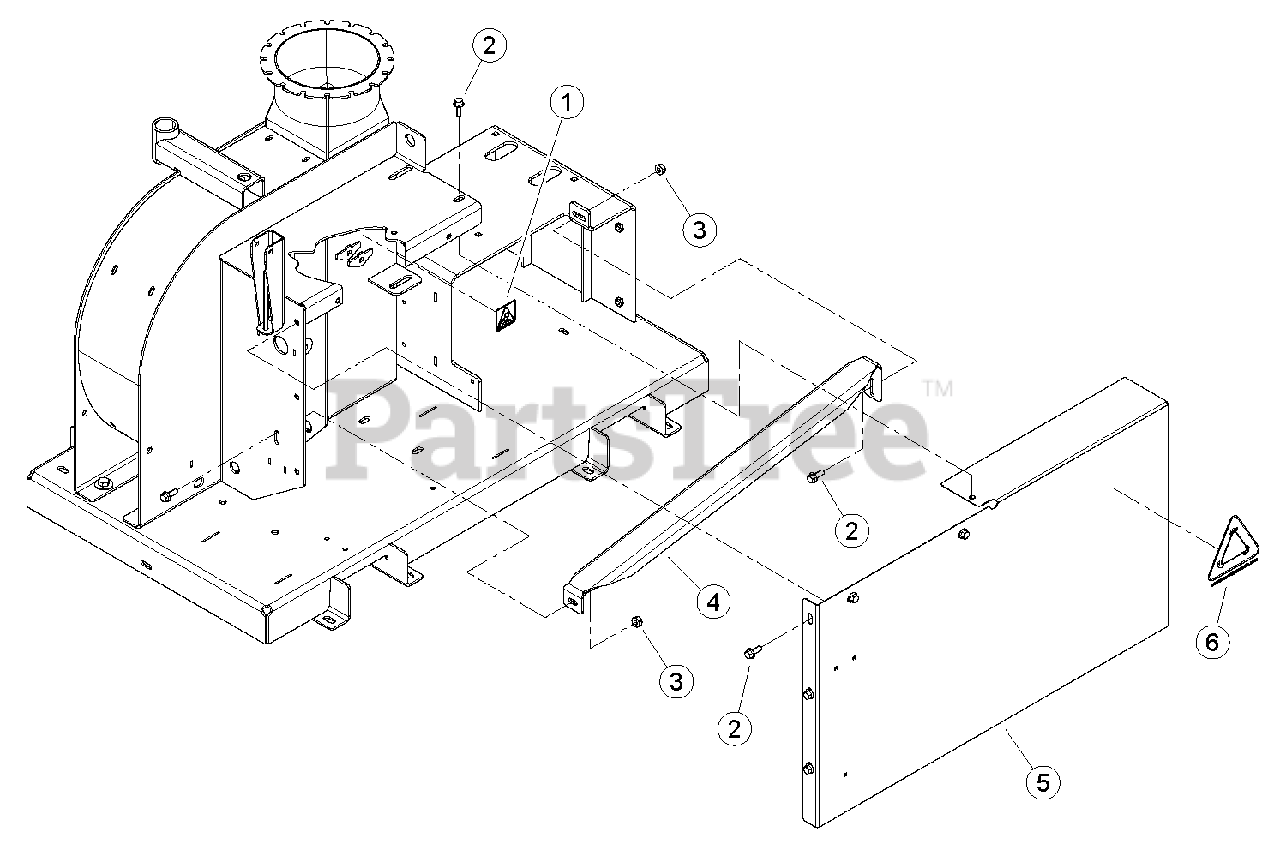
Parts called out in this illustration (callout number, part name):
1	DECAL, SHIELD DANGER ISO
2	BOLT, 3/8 X 1 FLANGE NC
3	NUT, 3/8-16 NYLOCK FLANGE
4	GUIDE, BELT
5	ASSEMBLY, BELT SHIELD
6	LOGO, COLLECT IT (WHITE)
